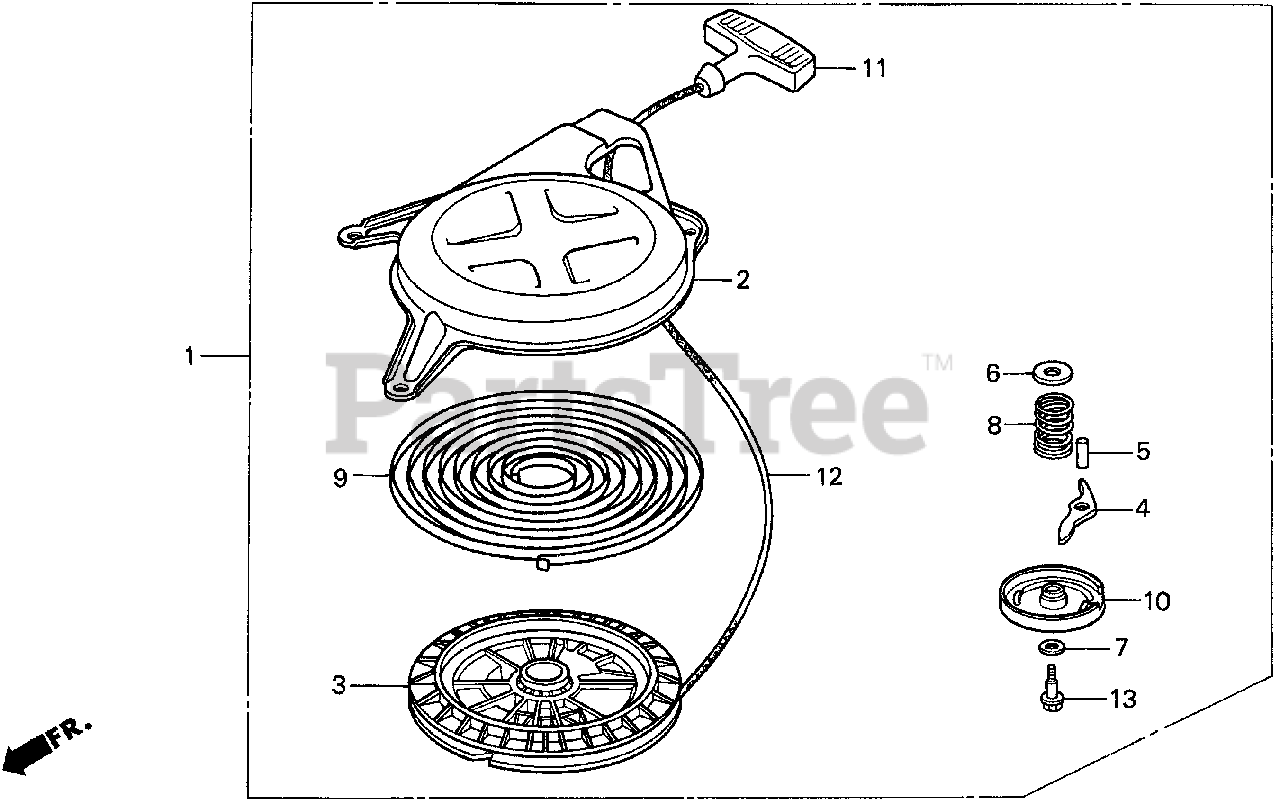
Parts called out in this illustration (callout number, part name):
1	STARTER ASSY., RECOIL
2	CASE, STARTER (NOT AVAILABLE)
3	REEL, STARTER
4	RATCHET, STARTER
5	SHAFT, RATCHET
6	PLATE A, FRICTION
7	PLATE B, FRICTION
8	SPRING, FRICTION
9	SPRING, RETURN
10	COVER, REEL STARTER
11	GRIP, STARTER
12	ROPE, STARTER (#4X65") (N/A: USE P/N 08540-ZG921-11)
13	BOLT, REEL COVER
